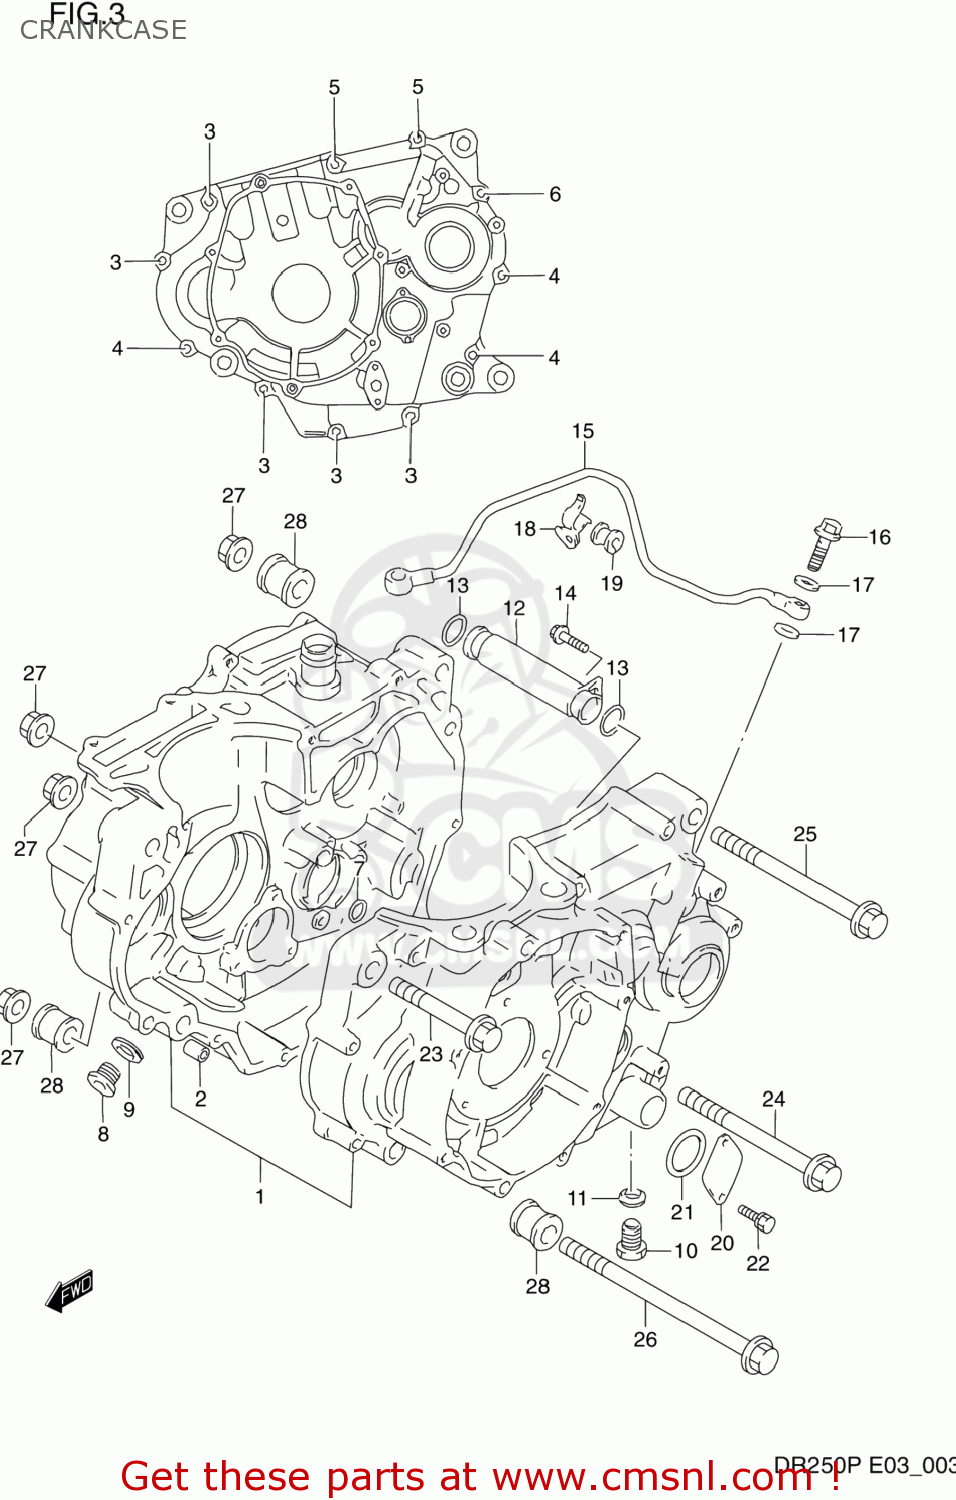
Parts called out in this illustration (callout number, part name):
1	CRANKCASE SET
2	PIN
3	BOLT
4	BOLT
5	BOLT
6	BOLT
7	O-RING
8	PLUG,14X12
9	GASKET(14X19.2X2) (NAS)
10	PLUG,OIL DRN.
11	GASKET(12.1X16.2X3.7) (NAS)
12	PIPE,T/M OIL INNER
13	O RING(D:2.4,ID:15.8)
14	BOLT
15	PIPE,T/M OIL OUTER
16	BOLT UNION
17	GASKET 8.2X14X1 (NAS)
18	CLAMP,OIL PIPE
19	CUSHION
20	CAP,NEUTRAL SWITCH HOLE
21	O RING(D:2.4,ID:26.2)
22	BOLT
23	BOLT 10X85
24	BOLT
25	BOLT(10X115)
26	BOLT
27	NUT
28	SPACER,ENGINE MOUNT
